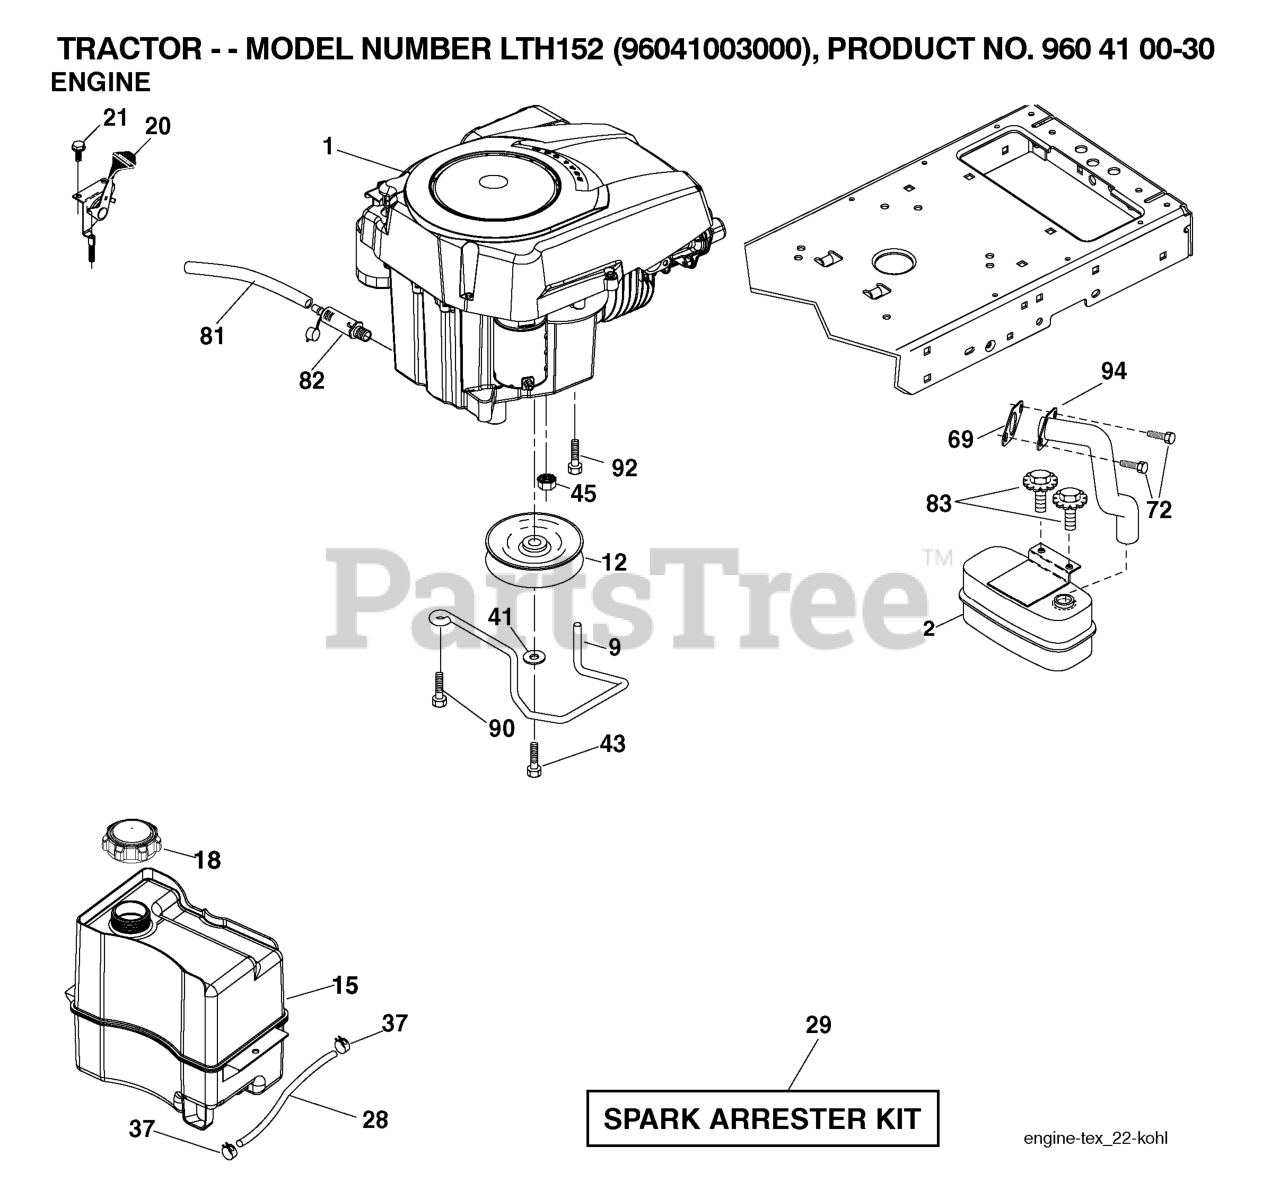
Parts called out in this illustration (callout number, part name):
2	MUFFLER.SINGLE.CYL.KOHL/B&S
9	KEEPER.BELT.ENGINE.3.25 (3 2)
12	PULLEY ENGINE
15	RP TANK FUEL FRT 1.5 GAL
18	FUEL CAP
20	CONTROL.TH/CK.C.
21	SCREW
28	LINE.FUEL.20
29	KIT.SPARK ARRESTOR 794945 B&S
37	HOSE CLAMP
41	LOCKWASHER
43	BOLT HEX 7/16-20X4-1/4"
45	NUT
69	GASKET.EXHAUST.KOHLER
72	SCREW.SOCKET HD.5/16-1
81	TUBE, DRAIN OIL ASM.
82	PLUG DRAIN OIL EASY
83	BOLT.5/16-18UNCX3/4 W/SEMS.BLK
90	SCREW 3/8-16X1
92	SCREW 3/8-16X1
94	RP.TUBE.EXHAUST.KOHL.COURAGE
97	SCREW HEXWSHR 1/4-20X3/4
